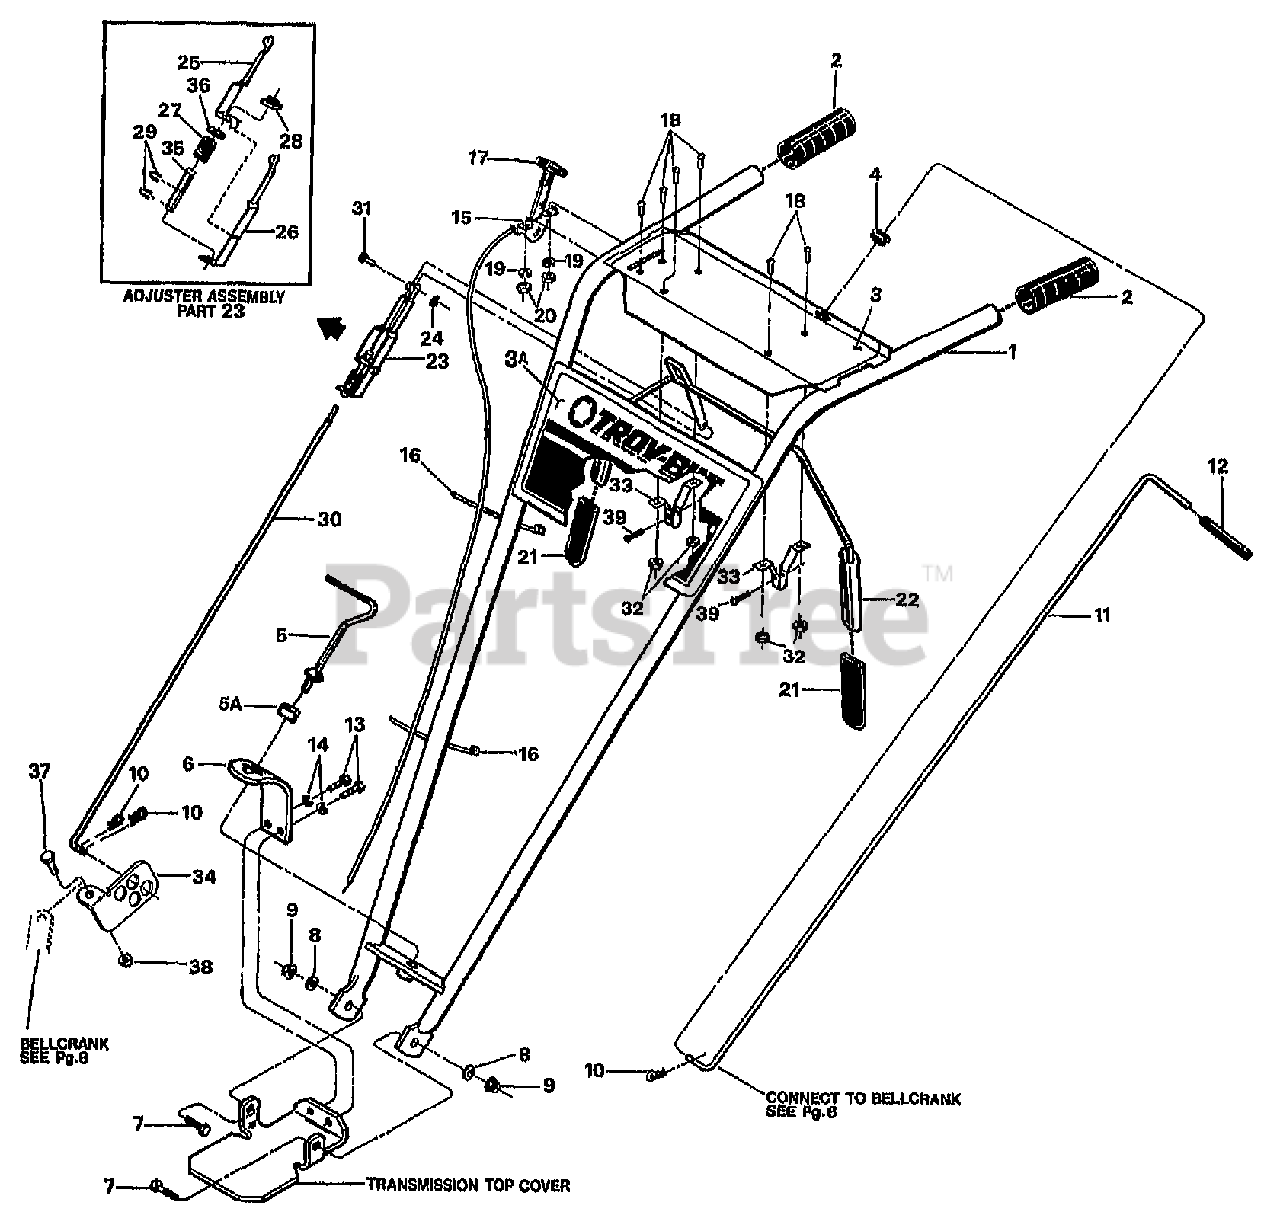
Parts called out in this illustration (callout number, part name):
1	ASSM-HANDLEBAR W/GRIPS (INCL. 2,3,3A,4)
2	GRIP-H/B 1" PONY/P-J OPC
3	DECAL-CONTROL PANEL JR
3A	DECAL-GRAPHICS PANEL JR (NAME & LOGO)
4	BUSHING-NYLON (PART OF OPERATOR CONTROL PANEL)
5	ASSM-STUD H/B (REGULATES HANDLEBAR HEIGHT ADJUSTMENT)
5A	WASHER-1.0X.38X.375 (INDEX #5)
6	PLATE-HANDLEBAR ADJUST
7	SCR-HH 3/8-16X1.0 G5
8	WASHER-FLAT 3/8 SAE (HANDLEBAR ATTACHMENT)
9	NUT-LOCK 3/8-16 NYLON (HANDLEBAR ATTACHMENT)
10	HAIR PIN COTTER
11	MANUVERING CLUTCH LEVER - COMPLETE (INCL. GRIP, #9198)
12	GRIP-CONTROL ROD
13	SCR-HH 3/8-16X.75 G5
14	WASHER-LK .375
15	CABLE-THROTTLE JR OPC
16	TIE-RED PLASTIC (TO SECURE THROTTLE CONTROL CABLE TO HANDLEBARS)
17	KNOB-THROTTLE CABLE
18	SCR-RH M10-32X.5 MACH
19	WASHER-LK N10
20	NUT-HH M10-32X.125
21	GRIP-PADDLE SM FRAME OPC
22	BAIL W/GRIPS OPC (INCL. TWO GRIPS, INDEX NO. 21)
23	ASSM-ADJUSTMENT OPC (INCL. 25-27,29,35,36)
24	RING-KLIP .188 DIA
25	ADJUSTER-RT SIDE OPC
26	ADJUSTER-LT SIDE OPC
27	SPRING-ADJUSTER OPC
28	WELDNUT 5/16-18
29	RING-KLIP .500 ZINC
30	ROD-CONTROL OPC - FORWARD CLUTCH
31	ASSM-PIN & CLIP (SMALL FRAME)
32	NUT W/LKWASHER #10-32
33	BRACKET-BAIL OPC
34	SWIVEL-SMALL FRAME
35	BUSHING-.5X.334X2.88
36	WASHER-.75X.51X.06
37	SCR-HH 1/4-20X.75 G5
38	NUT-LK 1/4-20
39	SCR-HWH 1/4-20 X .5 STH
